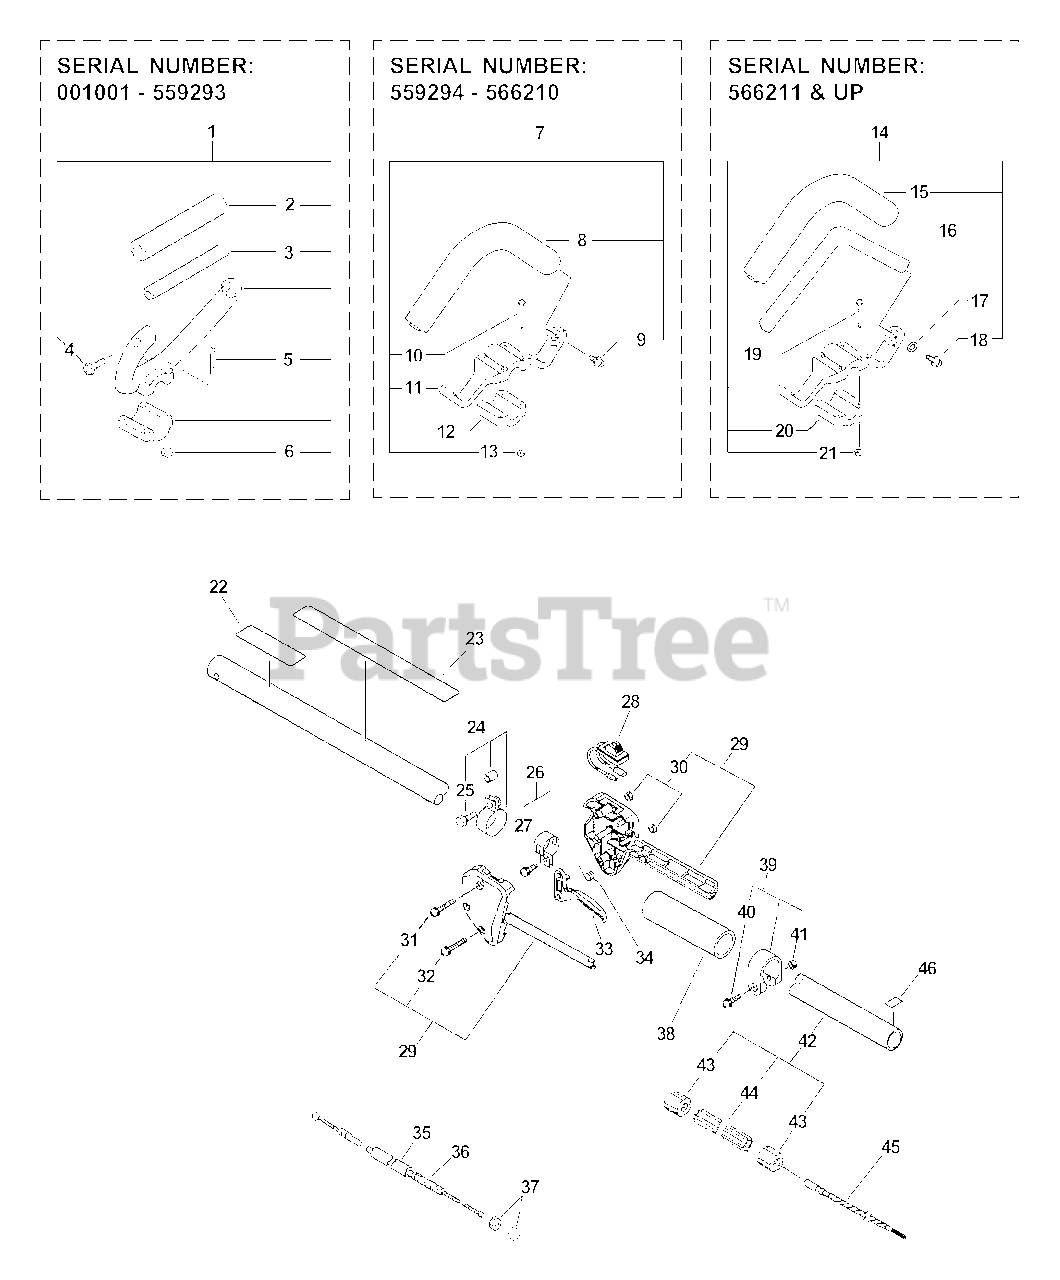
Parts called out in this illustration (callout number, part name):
1	LOOP HANDLE ASSY
2	GRIP, HANDLE
3	HANDLE
4	SCREW - 5X30
5	SCREW - 5X35
6	NUT - 5
7	HANDLE ASSY - FRONT
8	HANDLE - FRONT
9	SCREW - 5X14
10	SCREW - 5X35
11	BRACKET, HANDLE - UPPER
12	BRACKET, HANDLE - LOWER
13	NUT - 5
14	HANDLE ASSY - FRONT
15	GRIP, HANDLE
16	HANDLE - FRONT
17	WASHER - 5
18	SCREW - 5X20
19	SCREW - 5X35
20	BRACKET, HANDLE - LOWER
21	NUT - 5
22	LABEL - CAUTION -- SPANISH
23	LABEL - CAUTION
24	CLAMP
25	BOLT - 5X18
26	CLAMP KIT
27	SCREW - 5X14
28	IGNITION SWITCH ASSY
29	CONTROL HANDLE KIT
31	SCREW - 5X35
32	SCREW - 5X25
33	TRIGGER, THROTTLE
34	SPRING, TRIGGER
35	TUBE
36	CABLE, THROTTLE
37	NUT - 6
38	GRIP, HANDLE
39	CLAMP KIT
40	SCREW - 5X28
42	MAIN PIPE ASSY
44	LINER - FLEXIBLE
45	DRIVESHAFT - FLEXIBLE
46	LABEL - ALIGNMENT
